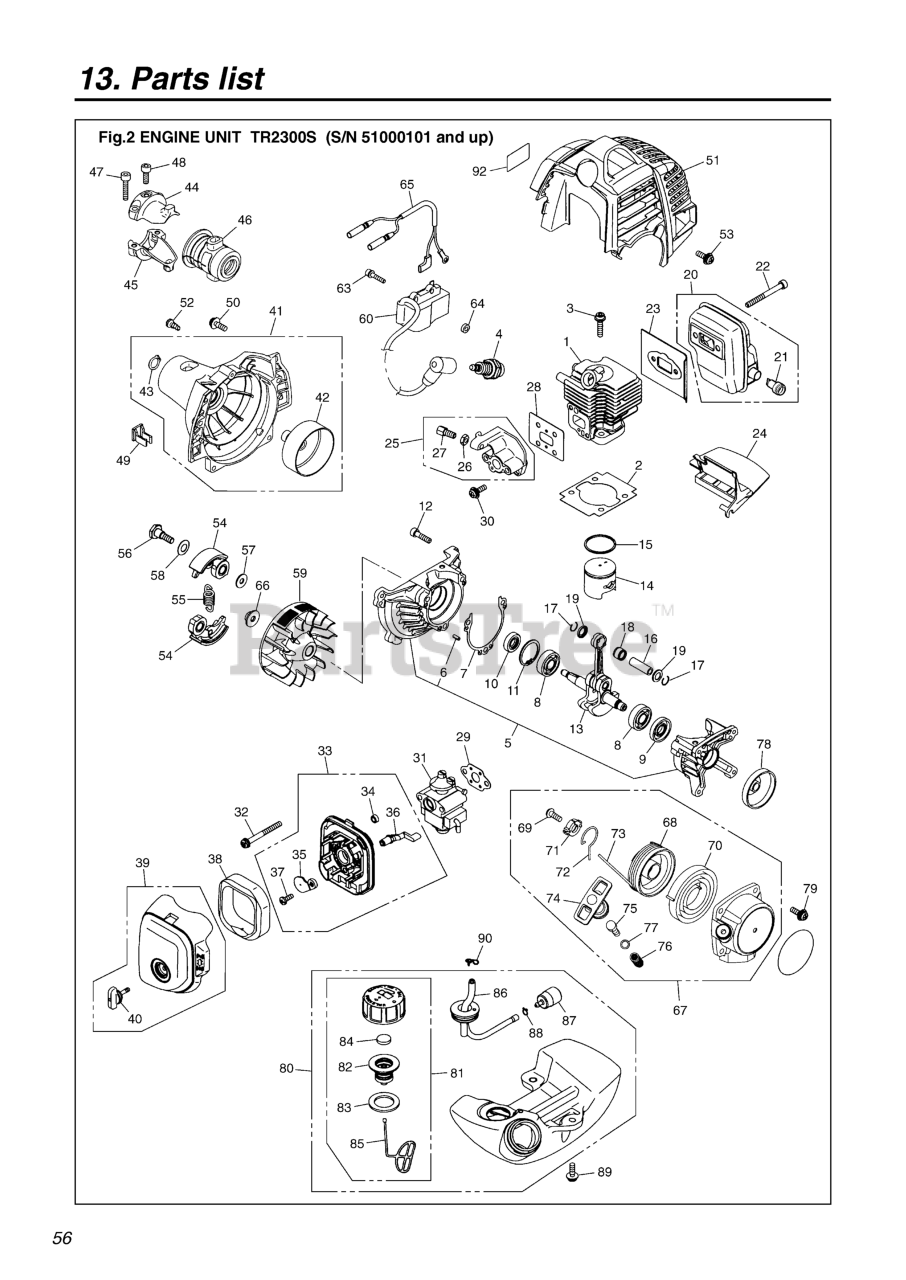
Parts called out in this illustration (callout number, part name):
1	CYLINDER
2	GASKET, BASE
3	BOLT, M5 X 22
4	PLUG (BPMR7A)(RPLS 5933-73110)
5	CRANKCASE-C
6	PIN
7	GASKET, CASE
8	BEARING
9	SEAL
10	SEAL
11	RING, SNAP M26x1.2 R-318013340
12	BOLT, M5 X 20
13	CRANKSHAFT-C
14	PISTON
15	RING, PISTON (RPLS 1850-41210)
16	PIN, PISTON 5x8x26
17	RING
18	BEARING
19	WASHER
20	MUFFLER-A
21	ARRESTER
22	BOLT, M5 x 50
23	GASKET
24	PLATE
25	INSULATOR-C
26	NUT
27	SCREW (RPLS 1918-81170)
28	GASKET (RPLS -13120)
29	GASKET (REPLACES -13130)
30	SCREW
31	CARBURETOR ASSY
32	SCREW (RPLS 0263-30550)
33	BODY ASSY.
34	SLEEVE
35	PLATE, CHOKE
36	LEVER
37	SCREW
38	ELEMENT
39	COVER-A
40	KNOB
42	DRUM
43	RING
44	BRACKET (A)
45	BRACKET (B)
46	CUSHION
48	BOLT
49	CLAMP
50	SCREW
51	COVER, ENGINE
52	SCREW, M5 X 10
53	SCREW
54	SHOE
55	SPRING
56	BOLT
57	WASHER
58	WASHER
59	ROTOR
60	COIL ASSY
63	BOLT, M4 x 20
64	SPACER
65	CORD COMP.
66	NUT
67	RECOIL-A
68	REEL
69	SCREW
70	SPRING
71	COLLAR
72	ARM
73	ROPE
74	KNOB
75	COLLAR
76	SPRING
77	WASHER
78	PULLEY
79	SCREW
80	TANK-A
81	CAP ASSY (RPLS. 5601-85201)
82	HOLDER - A (RPLS 5601-85230)
83	PACKING
84	FILTER
85	STOPPER
86	PIPE COMP
87	FILTER (RPLS 1850-85300)
88	CLIP
89	SCREW
90	CLIP
92	LABEL
NI	LABEL, RECOIL
